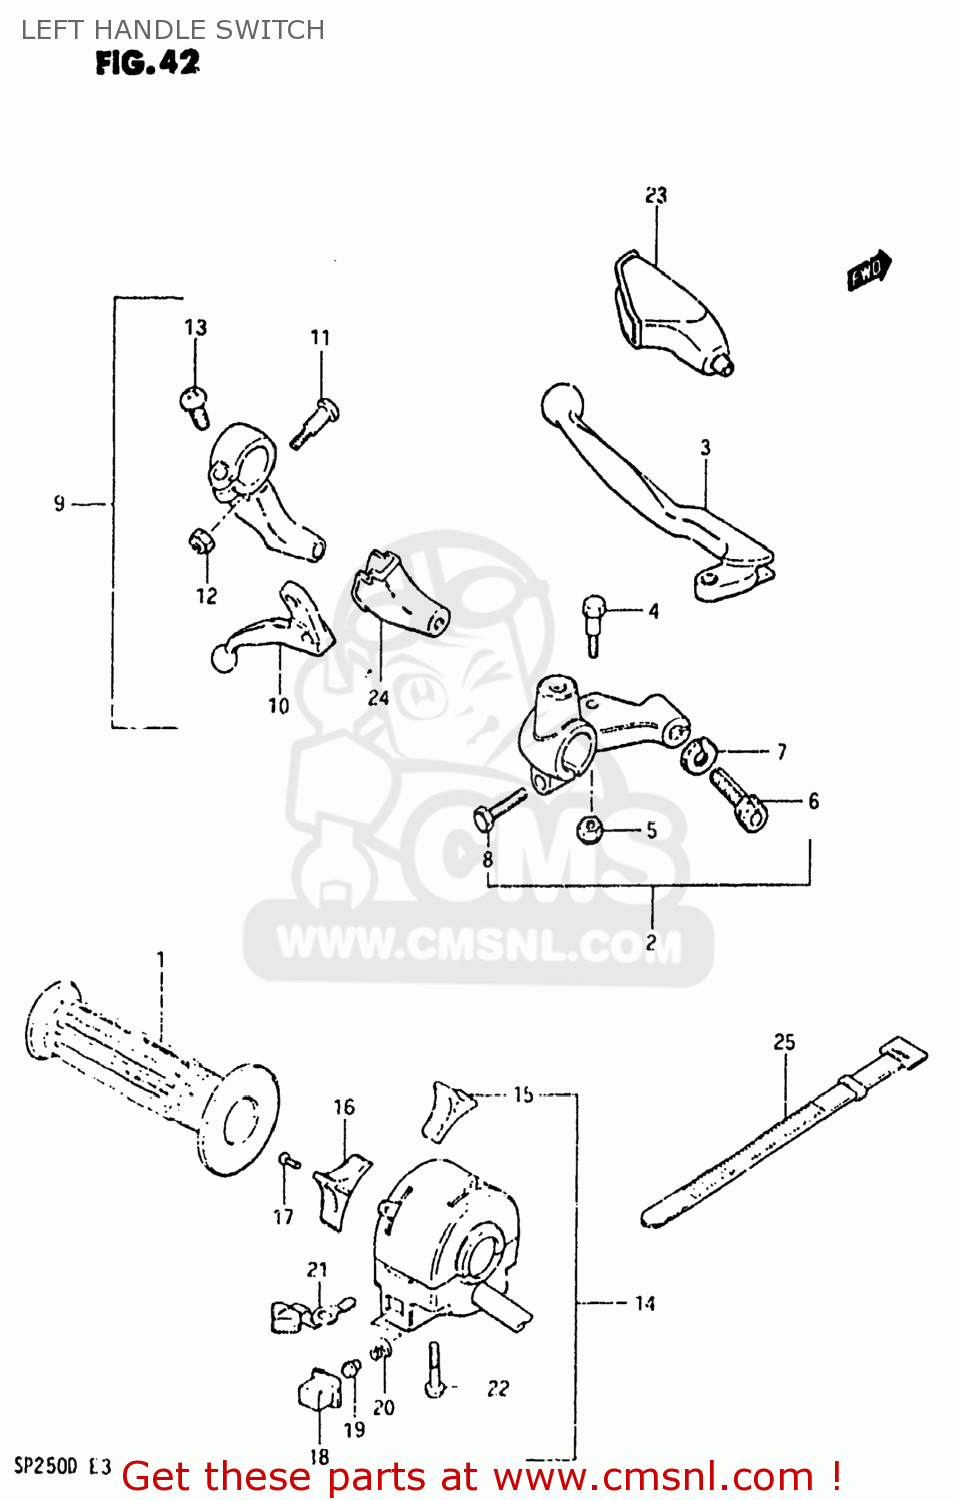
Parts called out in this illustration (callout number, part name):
1	GRIP,L
2	LEVER ASSEMBLY,CLUTCH
3	LEVER,CLUTCH
4	BOLT,LEVER
5	NUT 6MM
6	ADJUSTER,CABLE
7	NUT,CABLE ADJUSTER
8	BOLT,CLUTCH LEVER HOLDER
9	LEVER ASSEMBLY,DECOMPRESSION
10	LEVER,DECOMP
11	BOLT,LEVER
12	NUT
13	SCREW
14	SWITCH ASSEMBLY,HANDLE,LEFT
15	KNOB,STOP
16	KNOB,DIMMER SWITCH
17	SCREW
18	BUTTON,HORN
19	CONTACT
20	SPRING
21	KNOB,TURNSIGNAL
22	SCREW
23	COVER,CLUTCH LEVER
24	COVER,DECOMP LEVER DUST
25	CLAMP(L:120)
